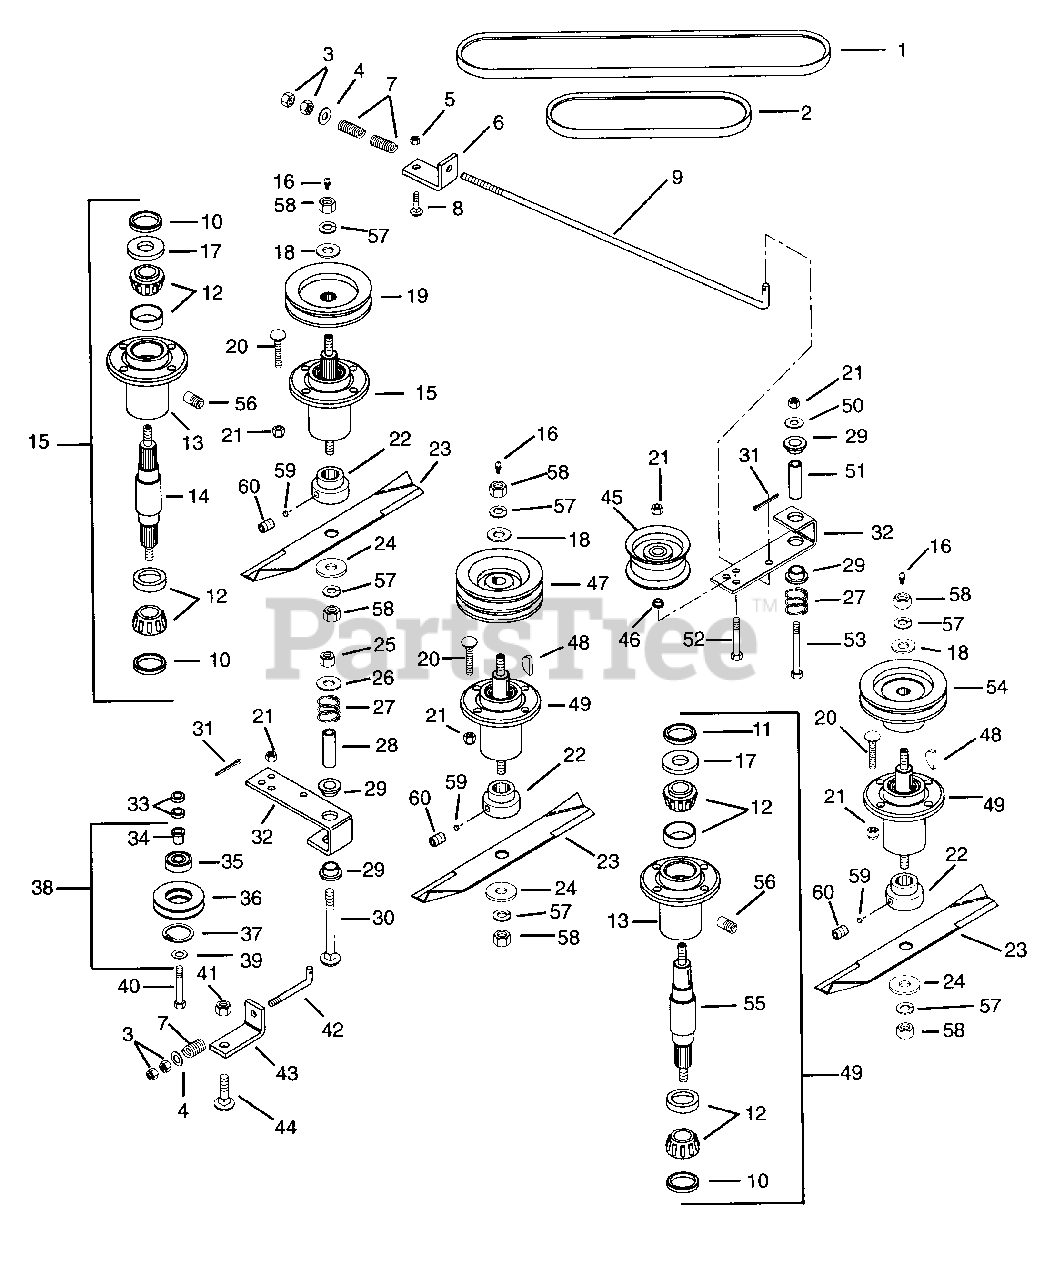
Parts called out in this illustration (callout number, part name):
1	Drive Belt 54.90 x 17/32
2	Right Spindle Belt 18.05 x .495
3	Nut-Hex .375 - 16 Grade 2
4	Washer-Flat-Steel .406 x .812 x .065
5	Nut-Locking-Center .31-18
6	Bracket, Belt Tensioner
7	Spring-Compression .125 x .78 x 1.00
8	Bolt-Round Head Square Neck .31-18 x 1.0 Grade 5
9	Rod-Idler L.H.
10	Seal 1.987 x 1.375 x .313
11	Seal 1.987 x 1.500 x .313
12	Assembly-Bearing Cup & Cone
13	Bearing Housing
14	Spindle Shaft
15	Service Kit Spindle Assembly
16	Fitting-Lube .25-28 x .256
17	Washer-Flat-Steel 1.007 x 1.542 x .062
18	Washer-Flat-Steel .687 x 1.312 x .150
19	Sheave
20	Bolt-Round Head Square Neck .38 - 16 x 1.50
21	Nut-Locking-Center .375 - 16
23	Blade 50 Inch Mower
24	Washer
25	Nut-Locking-Center .50 - 13
26	Washer-Flat-Steel .656 x 1.31 x .095
27	Spring-Compression .085 x 1.00
28	Bushing-Steel .560 x .750 x 2.44
29	Bushing-Flange .762 x 1.0 x .580 x 1.48
30	Bolt-Round Head Square Neck .50 - 13 x 3.50
31	Pin-Center .09 x .75
32	Arm-Idler Pivot
33	Bushing .406 x .750 x .188
34	Bushing-Flange .786 x 1.0 x .79
35	Bearing - Ball 1.85 x .787 x .55
36	Sheave-Idler
37	Ring-Retaining Internal 2.05 x .062
38	Assembly-Idler Sheave
39	Washer-Flat-Steel .406 x .812 x .065
40	Bolt-Hex .38-16 x 2.00 Grade 5
41	Nut-Locking-Center .50 - 13
42	Rod-Idler
43	Bracket-Belt Tensioner
44	Bolt-Round Head Square Neck .50-13 x 1.50 Grade 5
45	Idler-Flat 4 - .687 x .38
46	Bushing-Flange .406 x .88 x .270 x .140
47	Sheave
48	Key-Woodruff .25 x 1
49	Service Kit Spindle Assembly
50	Washer-Flat-Steel .438 x 1.0 x .083
51	Bushing-Steel .437 x .750 x 2.44
52	Bolt-Hex .38-16 x 2.50 Grade 5
53	Bolt-Hex .38-16 x 3.25 Grade 5
54	Sheave
55	Spindle Shaft
56	Relief Fitting
57	Washer-Locking .625 x .156
58	Nut-Hex .625-11 Grade 2
60	Screw-Set .25-20 x .25
